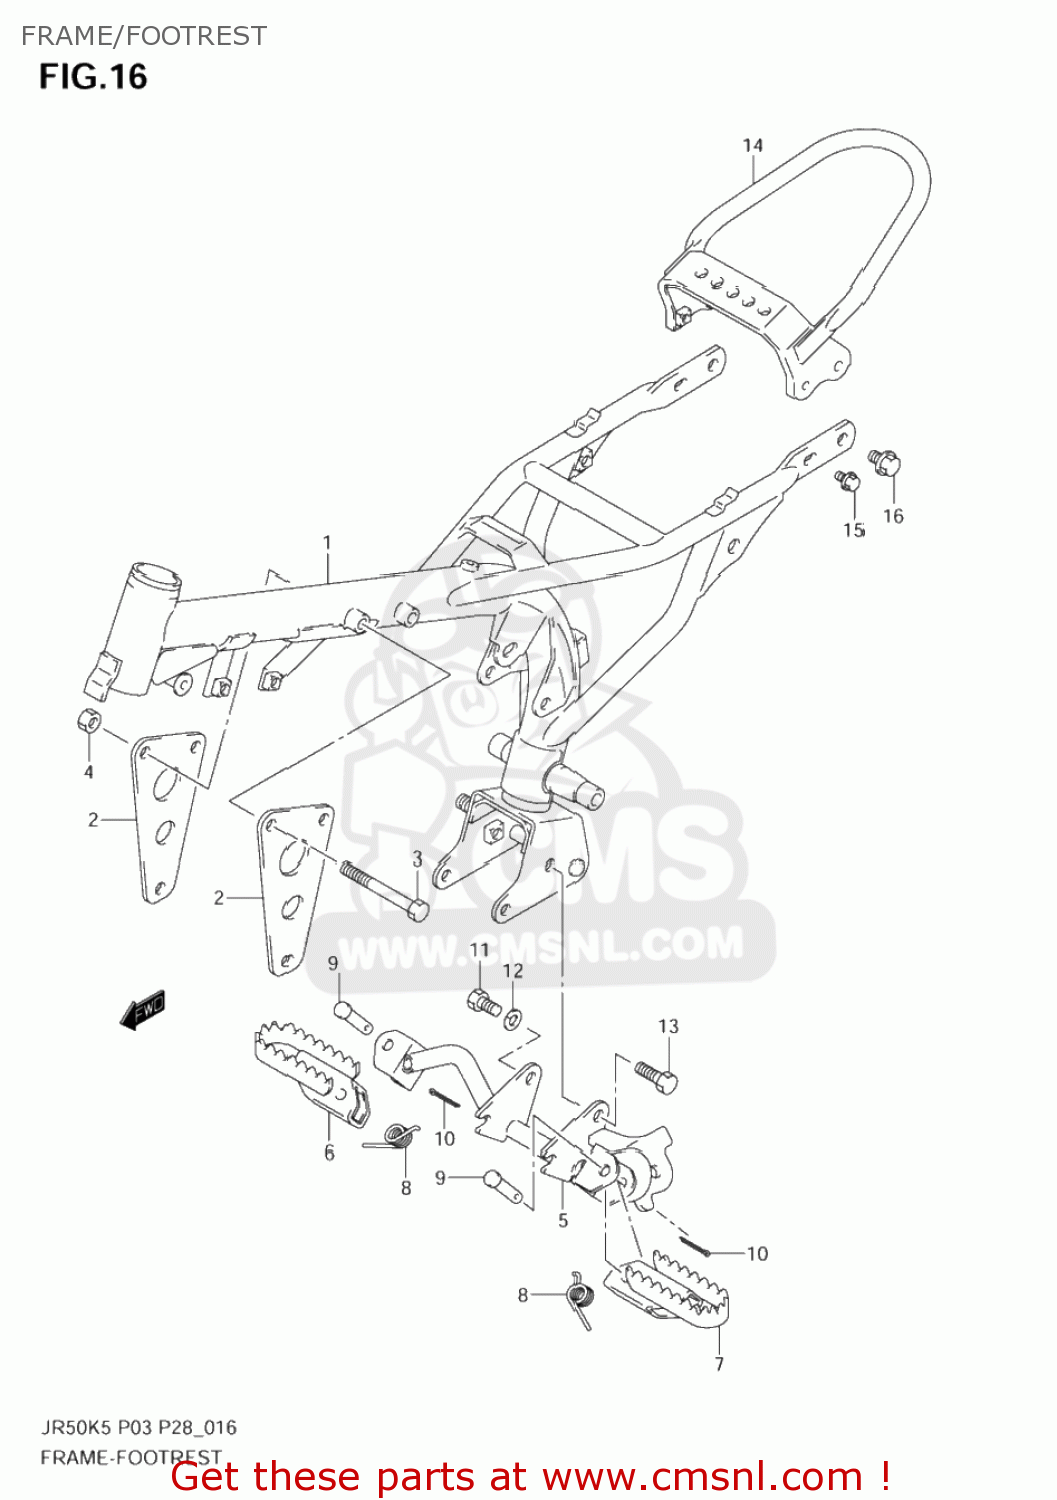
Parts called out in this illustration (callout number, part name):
1	FRAME(BLACK)
2	PLATE,ENG MTG
3	BOLT(8X70)
4	NUT
5	BAR,FR FOOTREST
6	FOOTREST,FR,R
7	FOOTREST,FR,L
8	SPRING
9	PIN
10	PIN
11	BOLT
12	LOCK WASHER
13	BOLT(8X14)
14	GRIP,RR
15	BOLT
16	BOLT
